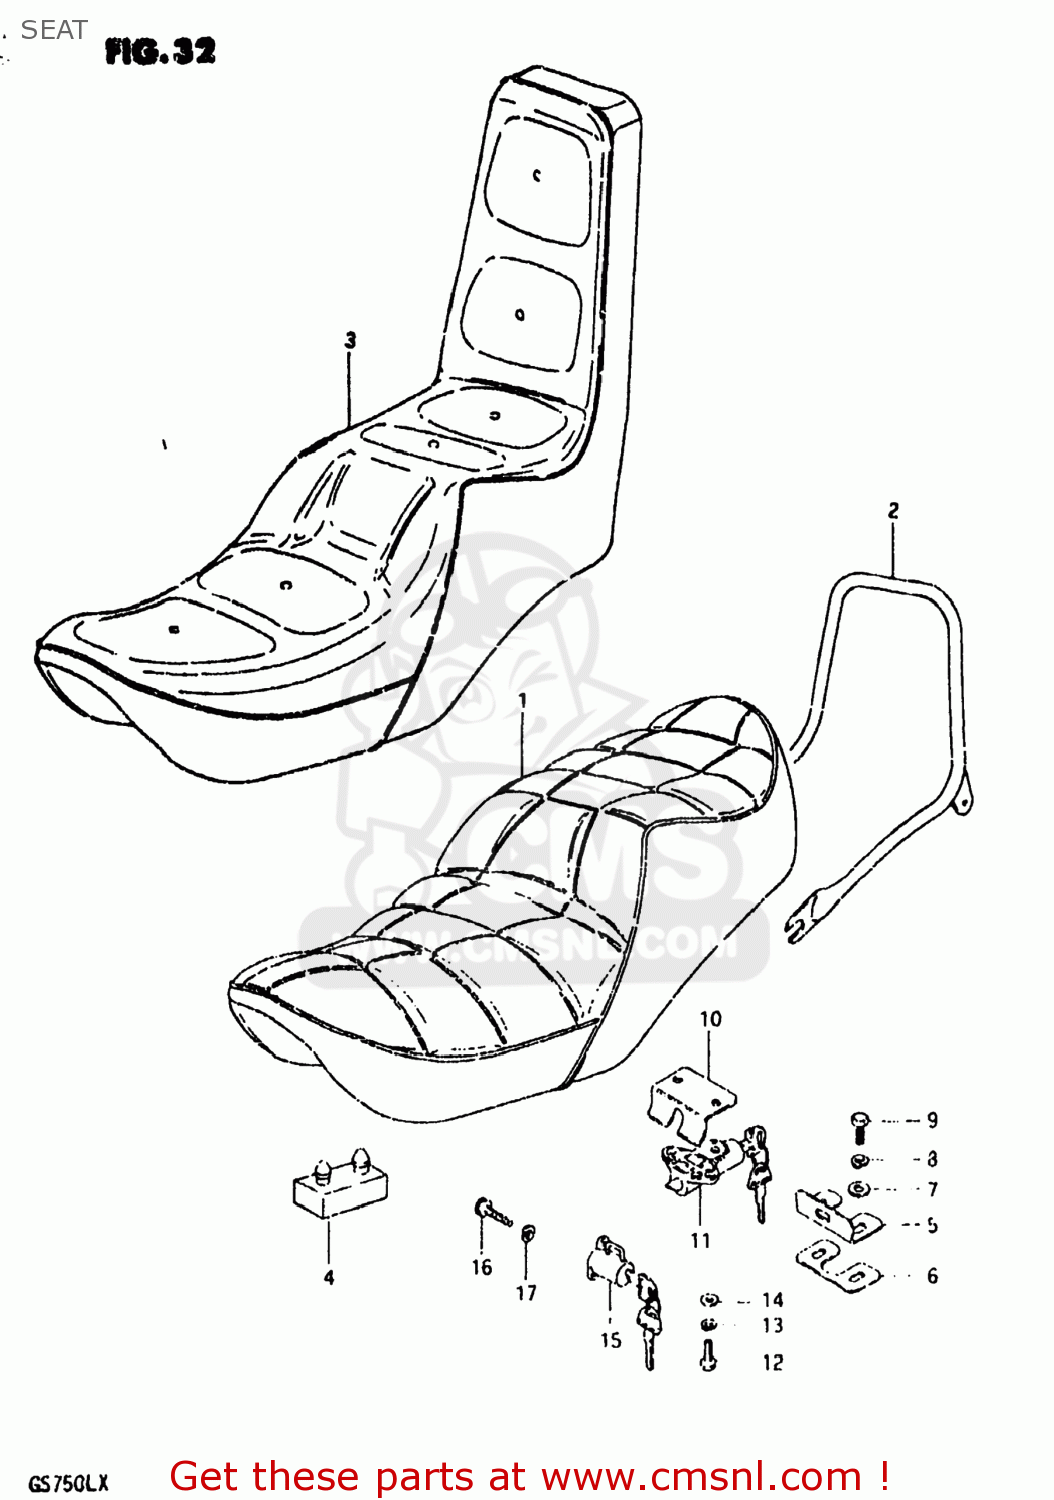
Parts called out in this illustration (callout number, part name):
1	SEAT ASSEMBLY
2	HANDLE,PILLION RIDER
3	SEAT ASSEMBLY
4	CUSHION
5	STRIKER,SEAT LOCK
6	SHIM,SEAT LOCK STRIKER
7	WASHER
8	LOCK WASHER
9	BOLT, UPPER
10	PLATE,SEAT LOCK
11	LOCK ASSEMBLY,SEAT
12	BOLT
13	LOCK WASHER
14	WASHER 6MM
15	LOCK ASSEMBLY,HELMET
16	STUD
17	LOCK WASHER
